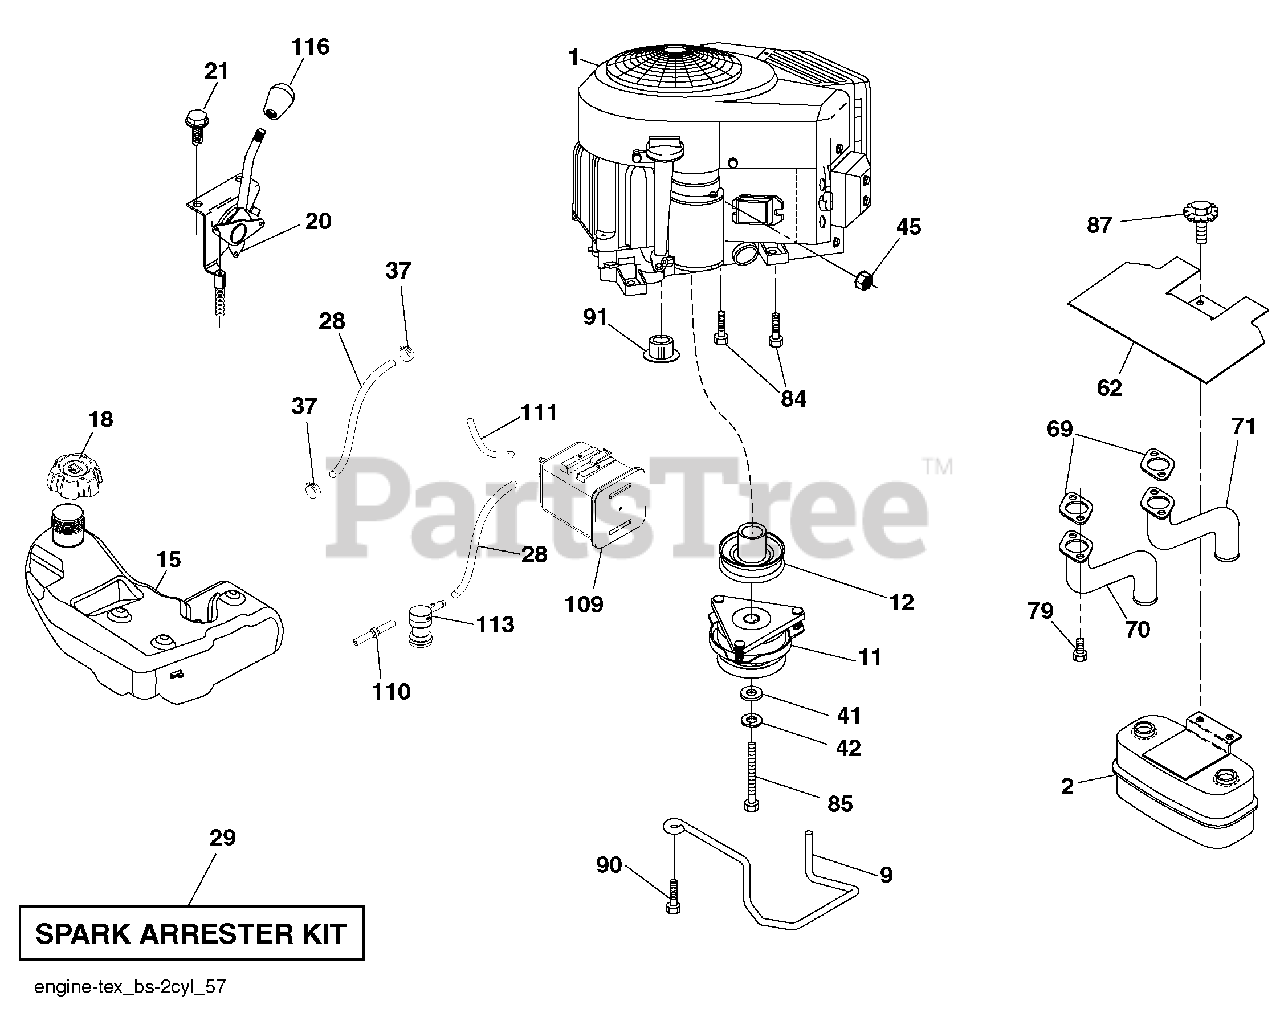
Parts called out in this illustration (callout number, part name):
9	Keeper Belt Engine
11	Clutch Electric
12	Pulley Engine
15	Tank Fuel
18	Cap Asm
20	Control Throttle
21	Screw #10 x .750 BOS Thread
28	Fuel Line
29	Spark Arrester Kit
37	Clamp Hose
41	Washer 1-1/2 OD x 15/32 ID x .250
42	Washer Lock 7/16
45	Nut Keps Hex 1/4-20 unc
62	Heat Shield
70	Tube Exhaust
71	Exhaust Tube
79	Screw Socket HP 5/16-18 x 1
84	Screw 3/8-16 x 1-1/4
85	Bolt Hex 7/16-20 x 4 x Gr. 5-1.5 Thr
87	Bolt 5/16-18 unc x 3/4 w/Sems
90	Screw 3/8-16 x 1
91	Bushing 1.375 OD
109	Canister Carbon Filter Asm.
110	Valve Anti Slosh
111	Purge Line
113	Valve Slant Cartrdg
116	Knob Soft Touch
